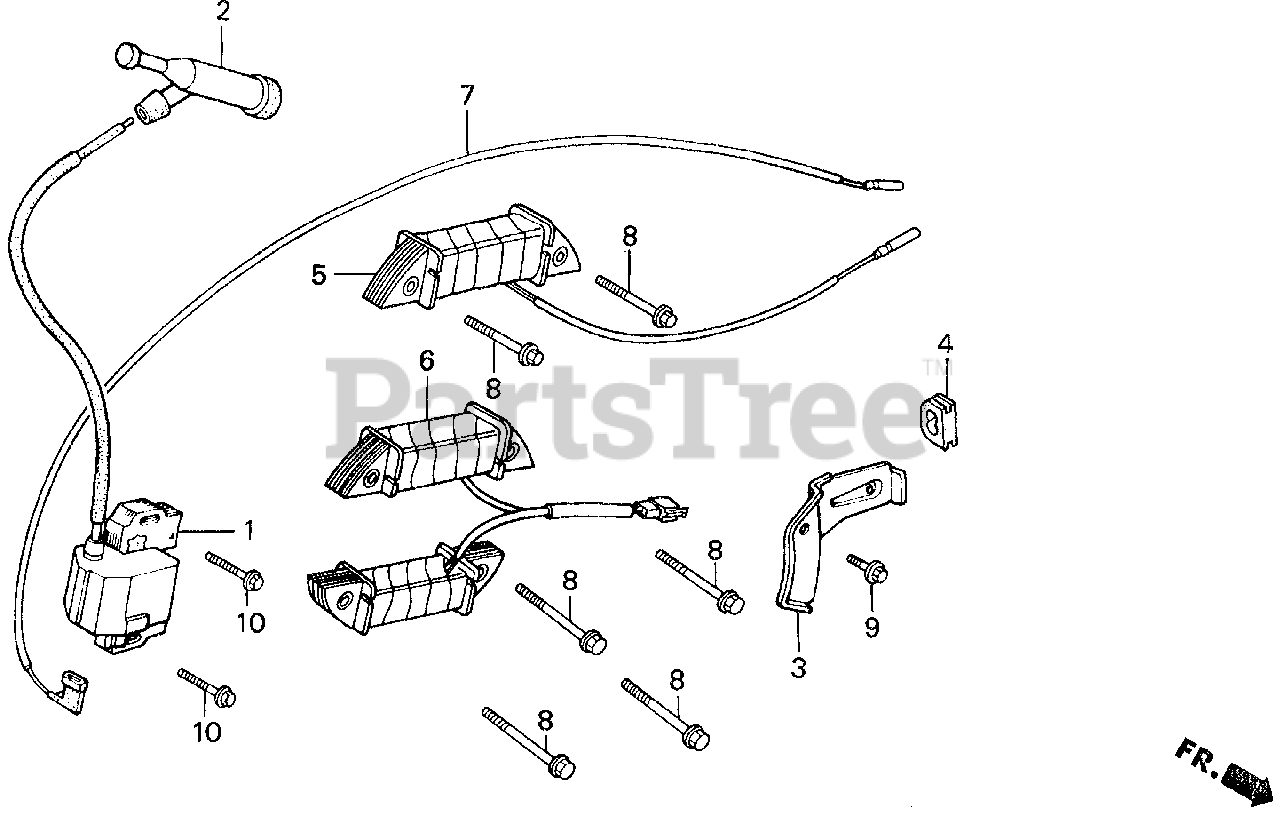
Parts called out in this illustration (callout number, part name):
1	COIL ASSY., IGNITION
2	CAP ASSY., NOISE SUPPRESSOR
4	GROMMET, WIRE
7	WIRE, STOP SWITCH (430MM)
10	BOLT, FLANGE (6X28)
